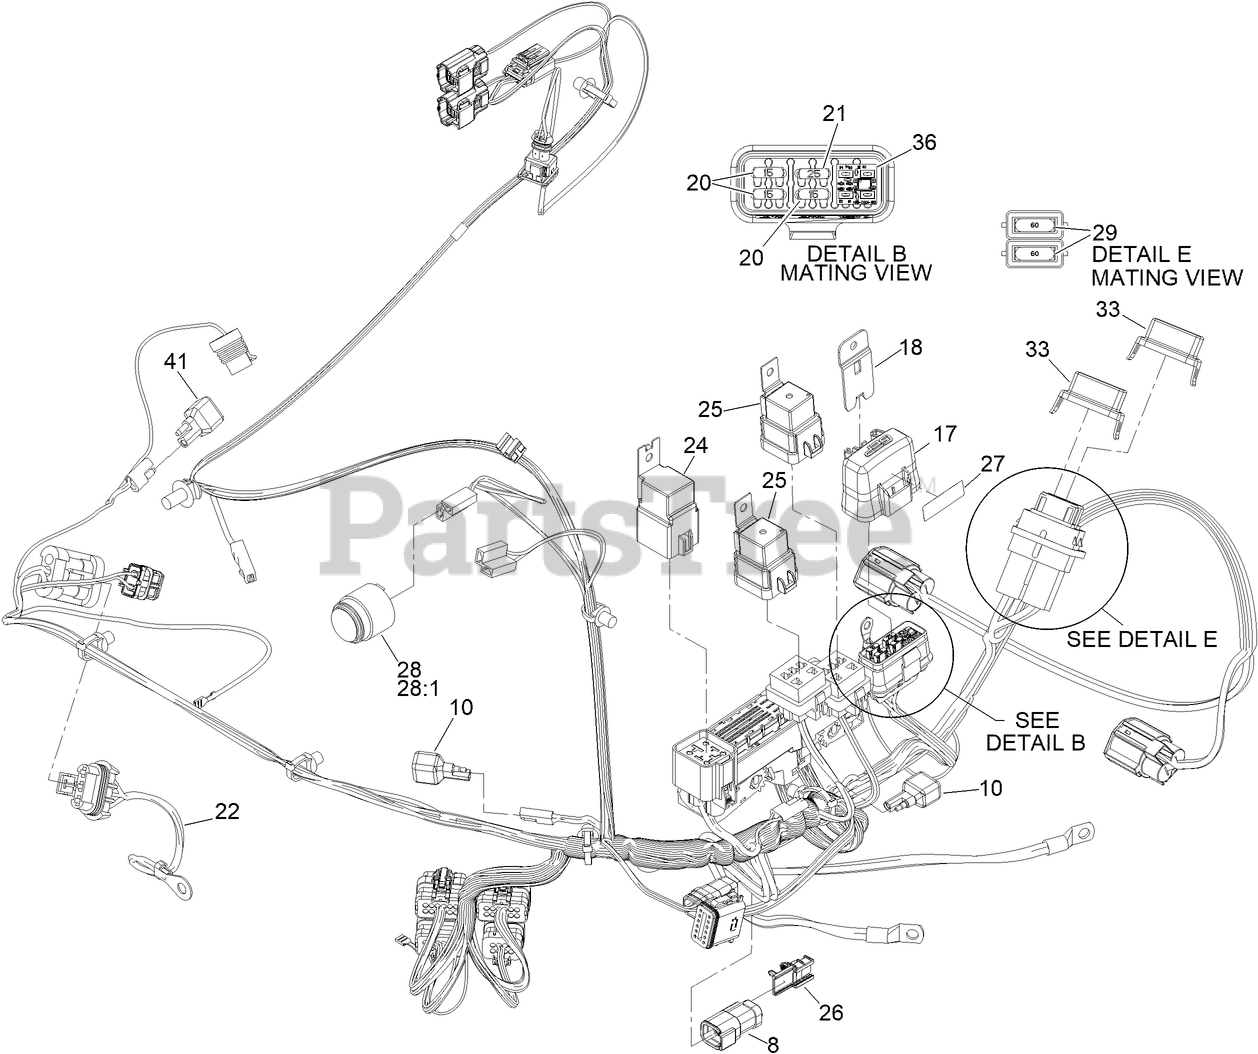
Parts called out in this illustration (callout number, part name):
8	Connector (6M)
17	COVER-BLOCK, FUSE
18	CLIP-MOUNTING
20	FUSE-MINI BLADE, 15 AMP
21	FUSE-MINI BLADE, 25 AMP
22	HARNESS-WIRE, FUSIBLE LIN
24	RELAY-70A
25	RELAY-MINI
26	CLIP-CONNECTOR
27	DECAL-FUSE
28	Audio Alarm ASM
28:1	Nut-Plastic, Knurled
29	FUSE-MAXI, 60 AMP
33	Cover-Fuse Holder, Maxi
36	RELAY-SOLID STATE, MP280, ASSEMBLY
41	RESISTOR-220 OHMS,2W,5%,OVERMOLDED
